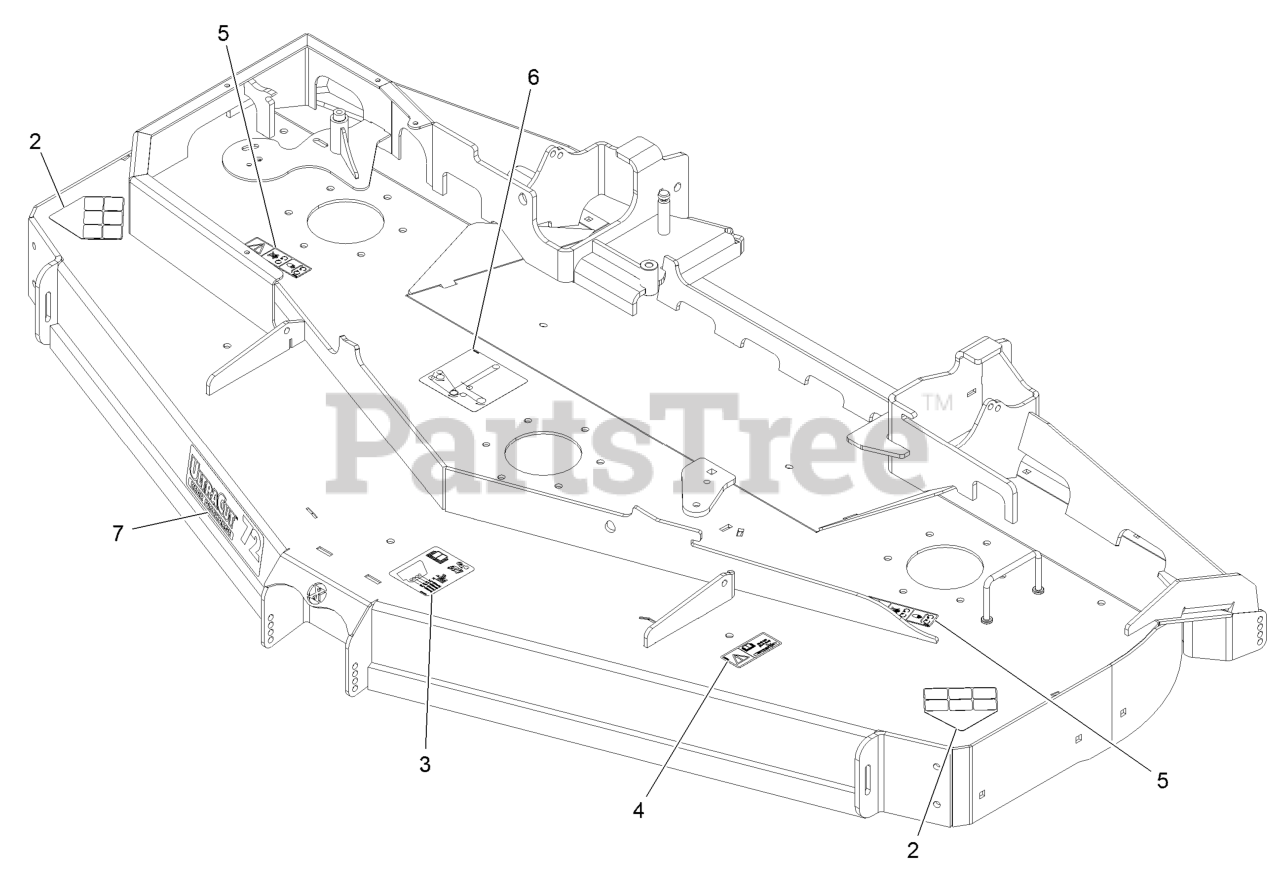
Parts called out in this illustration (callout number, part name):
2	DECAL-DANGER
3	DECAL-ROLLER, ANTI-SCALP
4	DECAL-BOLT TORQUE
5	DECAL-COVER, MISSING
6	DECAL-ROUTING, BELT
7	DECAL,REAR DISCHARGE 72
